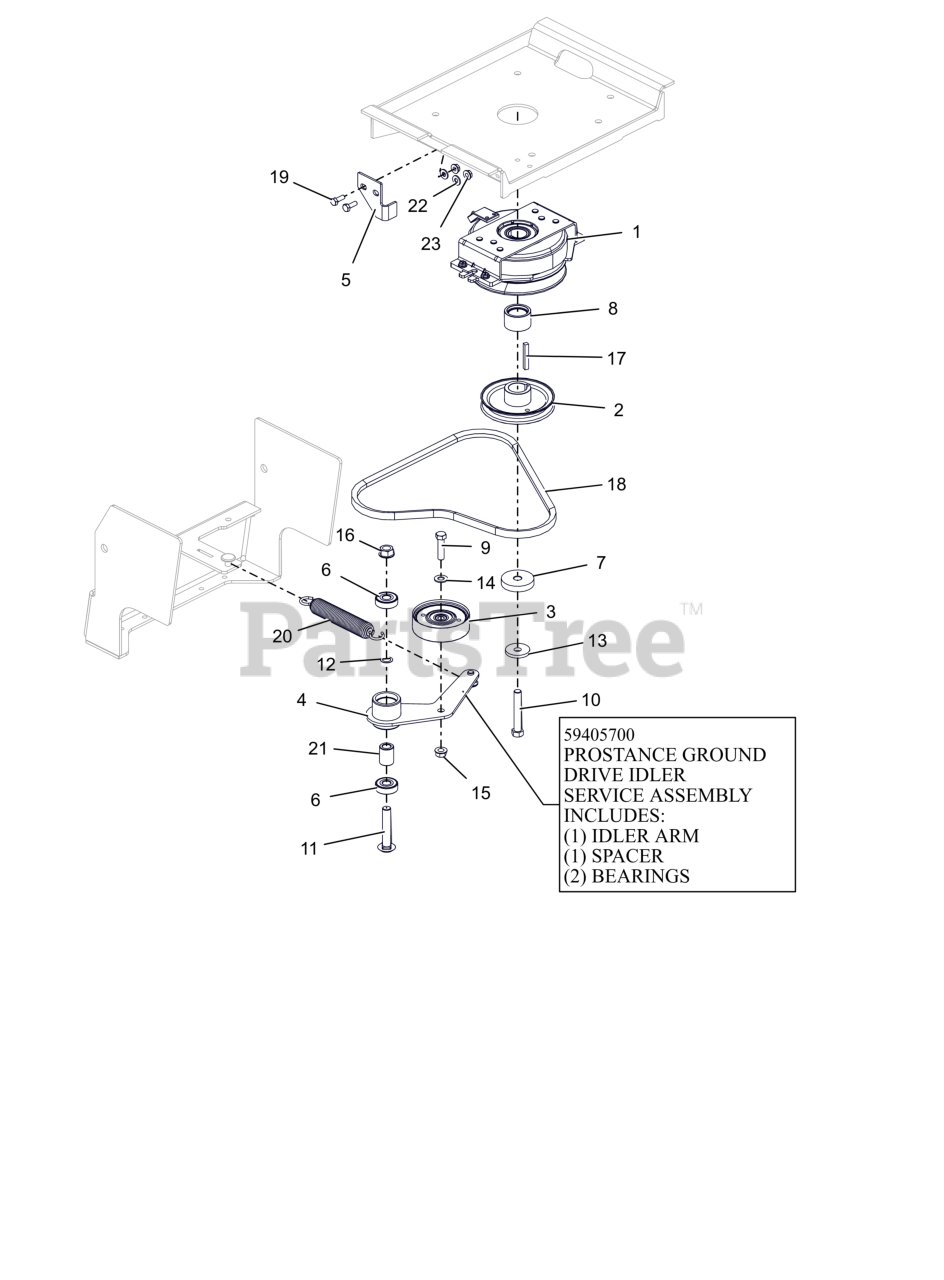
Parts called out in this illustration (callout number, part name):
1	CLUTCH, OGURA GT2.75-BBO1
2	SHEAVE, ENGINE 4.50 OD x 1.127 ID (BLACK)
3	IDLER, FLAT 3.5" NO FLANGES
4	WLDMT, IDLER ARM
5	BRKT, CLUTCH STOP (BLACK)
6	BRG-BALL .500X1.38X.437
7	SPACER, .450X2.00X.396
8	SPCR, CLUTCH
9	BLT, HEX .38-16X1.50 G5 ZCC
10	BLT, HEX 0.4375-20X2.75 G8 ZCC NT
11	BTL,RHSSN .500-13 X 3.25 G5 ZCC
12	WASHER, .500X.750X.020 THRUST
13	WASHER, 7/16" SPRING DISK
14	WSHR,FLT .406X.812X.065 ZCC
15	NUT-LK-CTR-FLG .375-16 GF ZCC
16	NUT-LK-CTR-FLG .500-13 GG ZCC
17	KEY-STR .25X1.75X.25
18	V-BELT, A -RAW EDGED LAMINATED
19	BLT, HEX .25-20X.75 G5 ZCC
20	SPRING, EXTENSION 1.0 X 6.65
21	SPACER .510 X .75 X 1.1485
22	WSHR,FLT .281X.625X.065 ZCC
23	NUT-LK-TOP-FLG .250-20 GF ZCC
